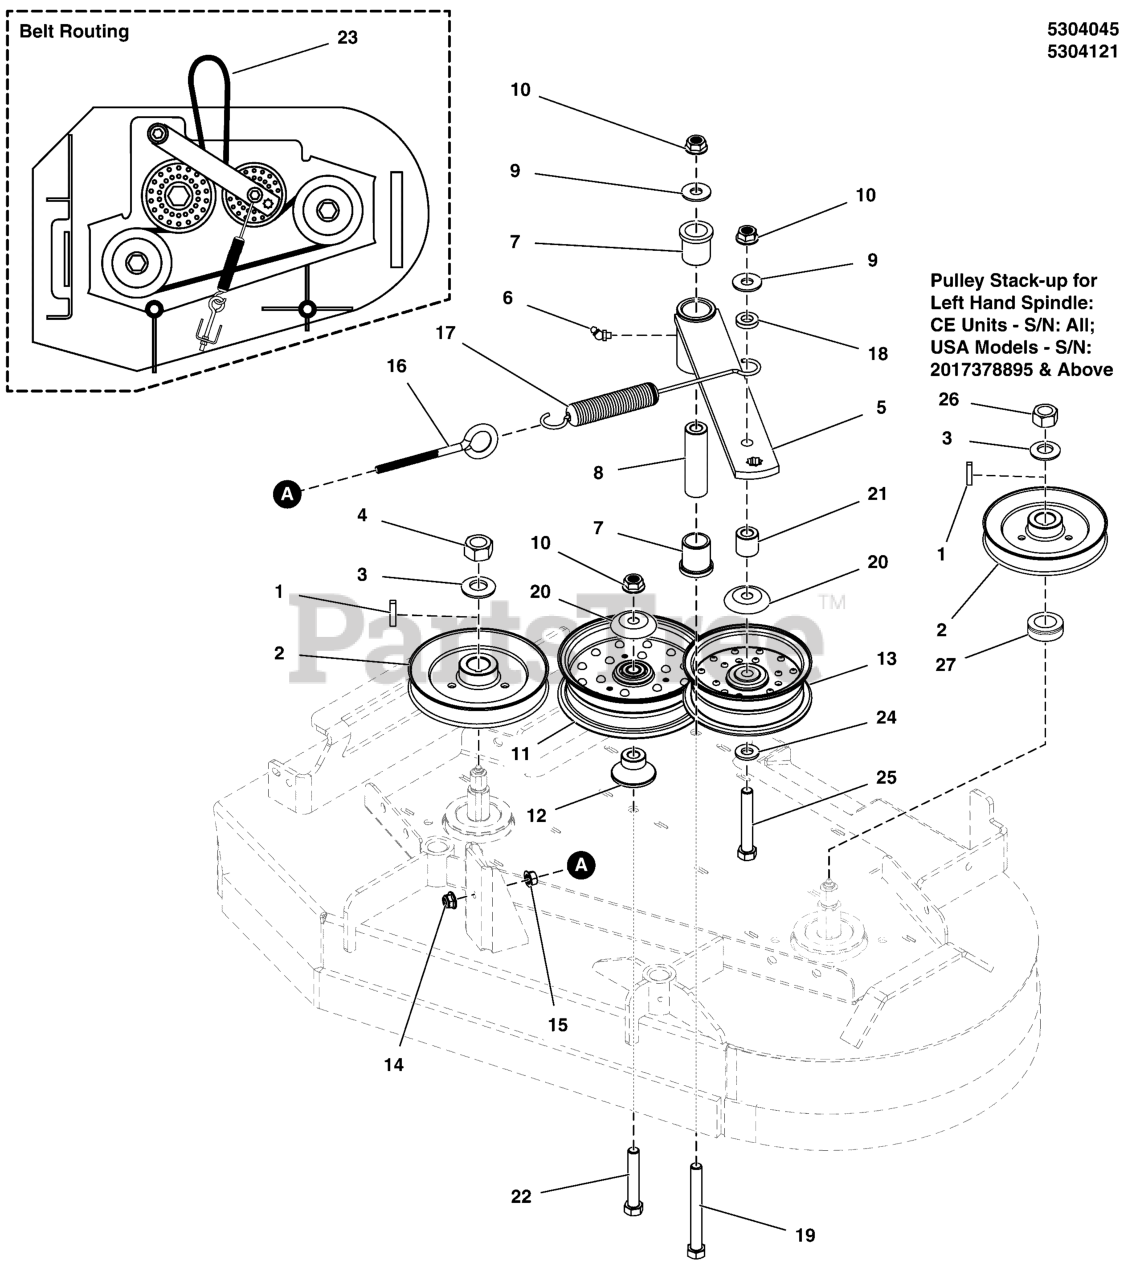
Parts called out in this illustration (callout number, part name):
1	KEY, 1/4 SQ X 1-1/4
2	PULLEY, 5.926 OVER BALL
3	WASHER, 3/4 BELLEVILLE
4	NUT, 3/4-16 HEX
5	WELD, IDLER ARM (10.50) - BLK
6	GREASE FITTING
7	BUSHING, FLANGE
8	SPACER, .52 X 1.00 X 3.50
9	WASHER, 1/2 USS
10	NUT, Hex Flange, Nylock, 1/2-13
12	IDLER MOUNT
13	PULLEY, IDLER, 5.00 WIDE W/ .51 BORE
14	NUT, 3/8-16 HEX NYLOCK FLANGE
15	NUT, 3/8-16 HEX SERRATED FLANGE
16	EYEBOLT, 3/8-16 X 4, 2.13THRD, .75EYE, C
17	SPRING-EXT, 1.04 ODX10.535LGX.148WR, BLK
18	SPACER, .52 X 1.00 X .38, CZ
19	BOLT, 1/2-13 X 5 GD5 CZ
20	SHIELD, PULLEY BEARING, CZ
21	SPACER, .52 X 1.00 X .88, PM, CZ
22	BOLT, 1/2-13 X 3" GD5 CZ
23	BELT, B-SEC, 97.6"EL, ARAMID, WRAPPED
24	WASHER, 1/2 GD9 CZ
25	BOLT, 1/2-13 X 3-1/4, HEX HD, GD5, CZ (SV)
26	NUT, 3/4-16, HEX NYLON LOCK
27	SPACER, 1.00 X 1.50 X .25, CZ
